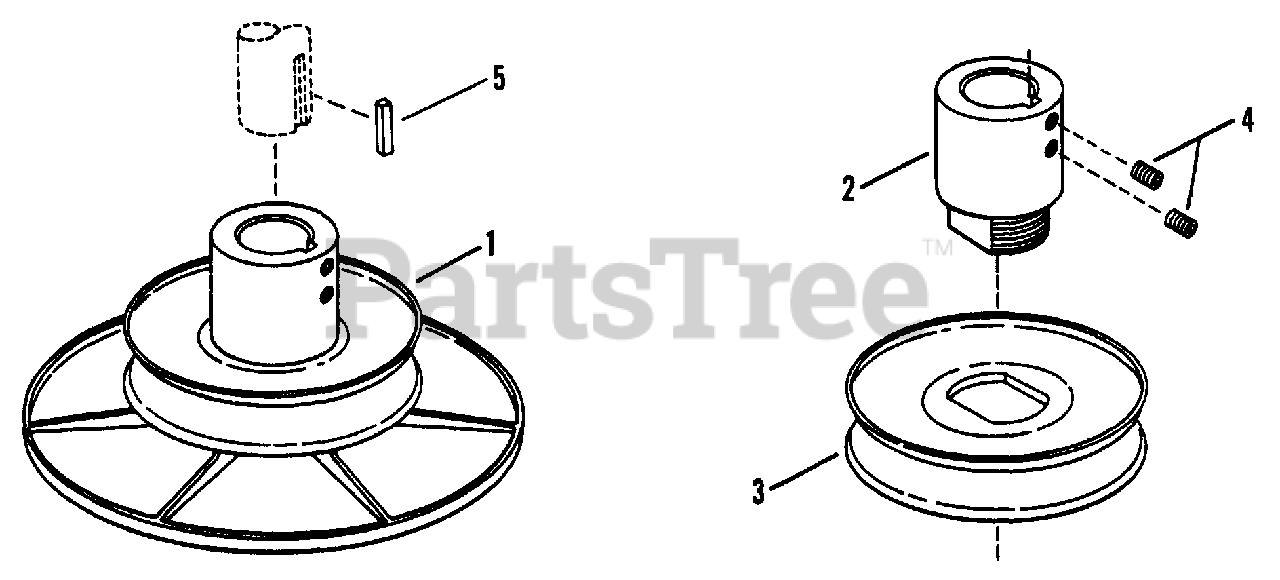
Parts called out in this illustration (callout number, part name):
1	ASSEMBLY, 4" O.D. Drive Disc
3	PULLEY, Drive
4	SCREW, 3/8-16 x 3/8" Set
5	KEY, 1/4" Square x 2"
